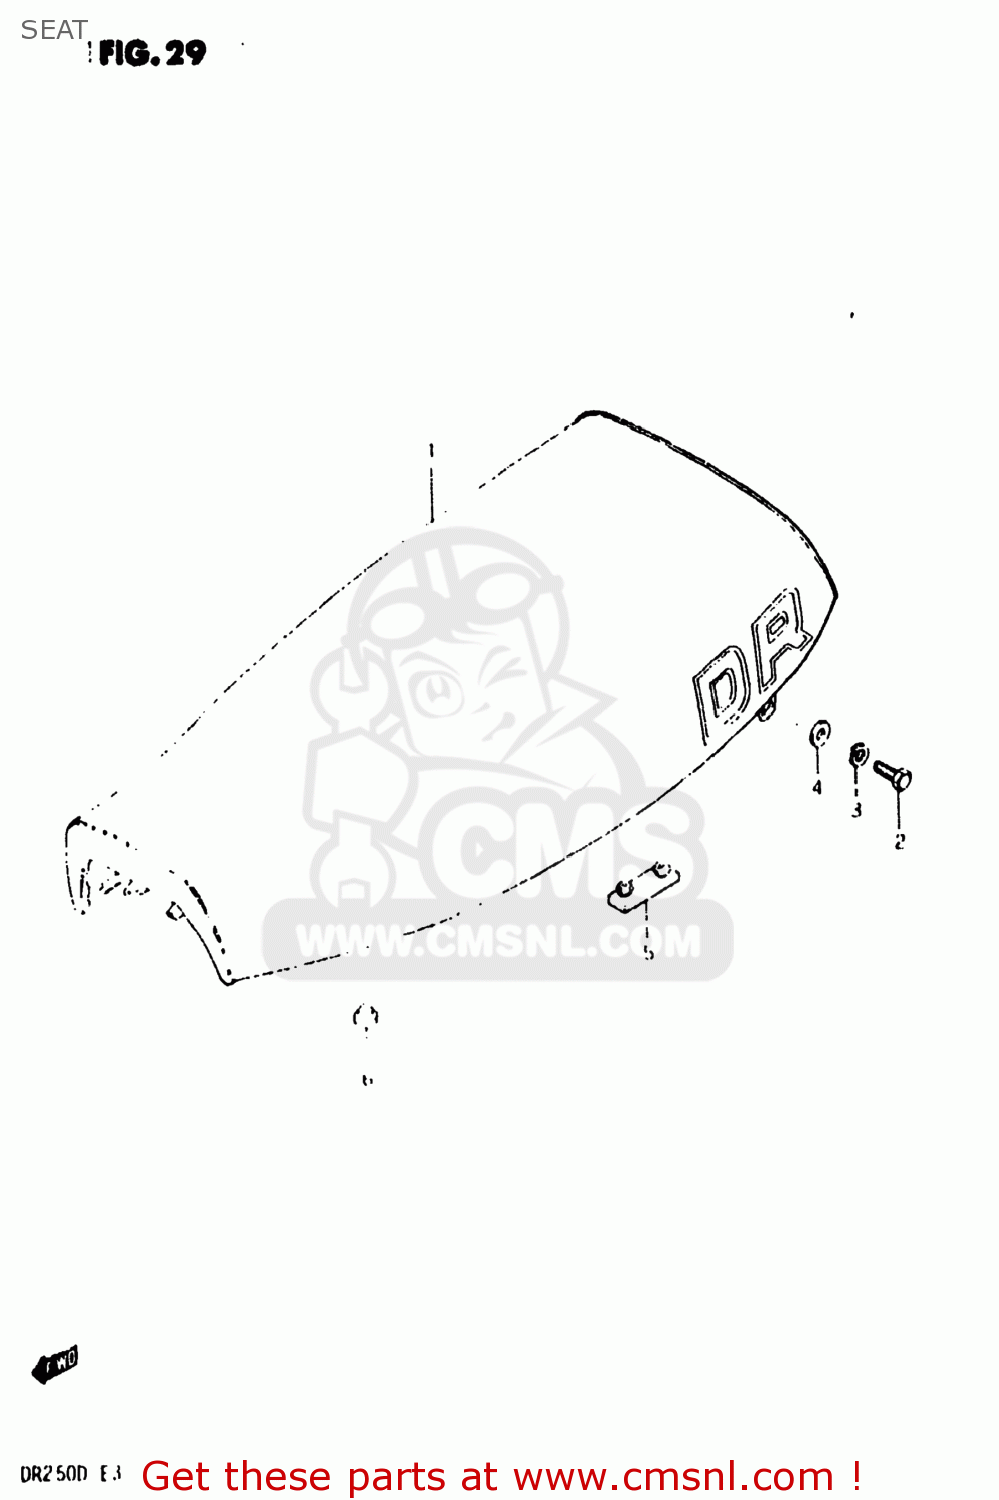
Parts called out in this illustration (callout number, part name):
1	SEAT ASSEMBLY
2	BOLT
3	LOCK WASHER
4	WASHER
5	CUSHION
6	CUSHION
